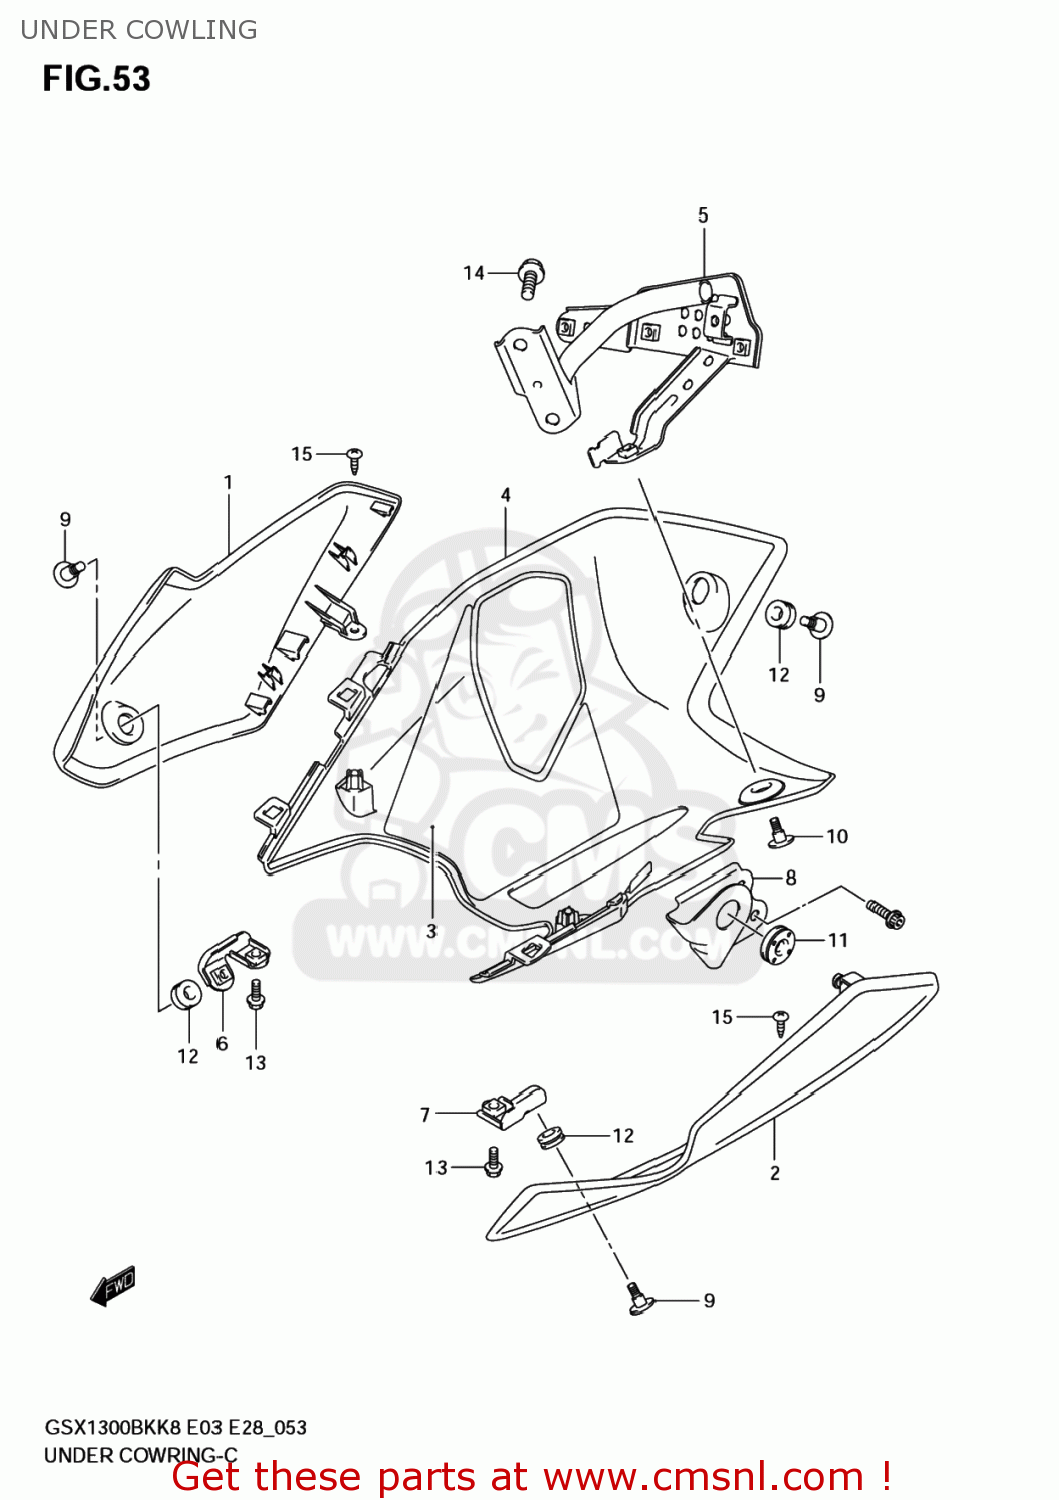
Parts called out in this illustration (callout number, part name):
1	COWLING,UNDER,R
2	COWLING,UNDER,L
3	HEATSHIELD,UNDER COWL CTR
4	COWLING,UNDER CTR
5	BRACE,UNDER COWLING
6	BRACKET,UNDER COWLING,R
7	BRACKET,UNDER COWLING,L
8	BRACKET,UNDER COWLING
9	SCREW(6X20)
10	SCREW(6X16)
11	CUSHION
12	CUSHION
13	BOLT
14	BOLT
15	SCREW
